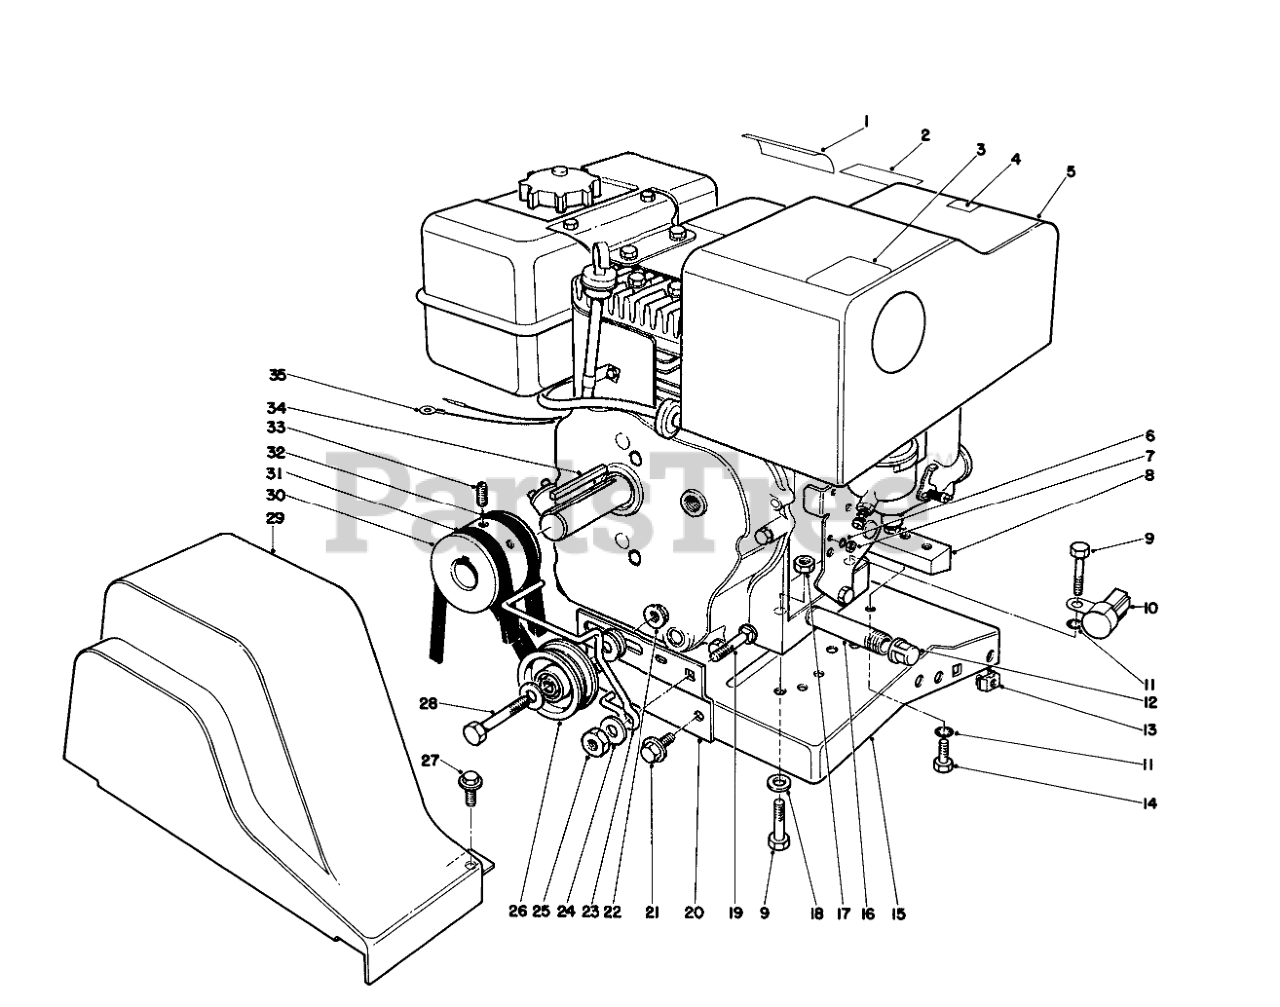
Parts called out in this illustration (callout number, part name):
1	CAUTION DECAL
5	Engine
6	WASHER-LOCK/INT
7	NUT-LOCK
9	SCREW-HH
10	INTERLOCK MODULE
11	WASHER-LOCK, INTERNAL
12	CAP-PIPE
14	SCREW-HH
16	NIPPLE-PIPE
17	NUT-LOCK, NI
18	WASHER-PLAIN
19	SCREW-CARR
21	SCREW-HWHTF
22	NUT-HHF, WHIZ
24	WASHER-FLAT
25	NUT-LOCK, NI
27	SCREW-HWH
28	SCREW-HH
31	V-BELT
32	V-BELT
